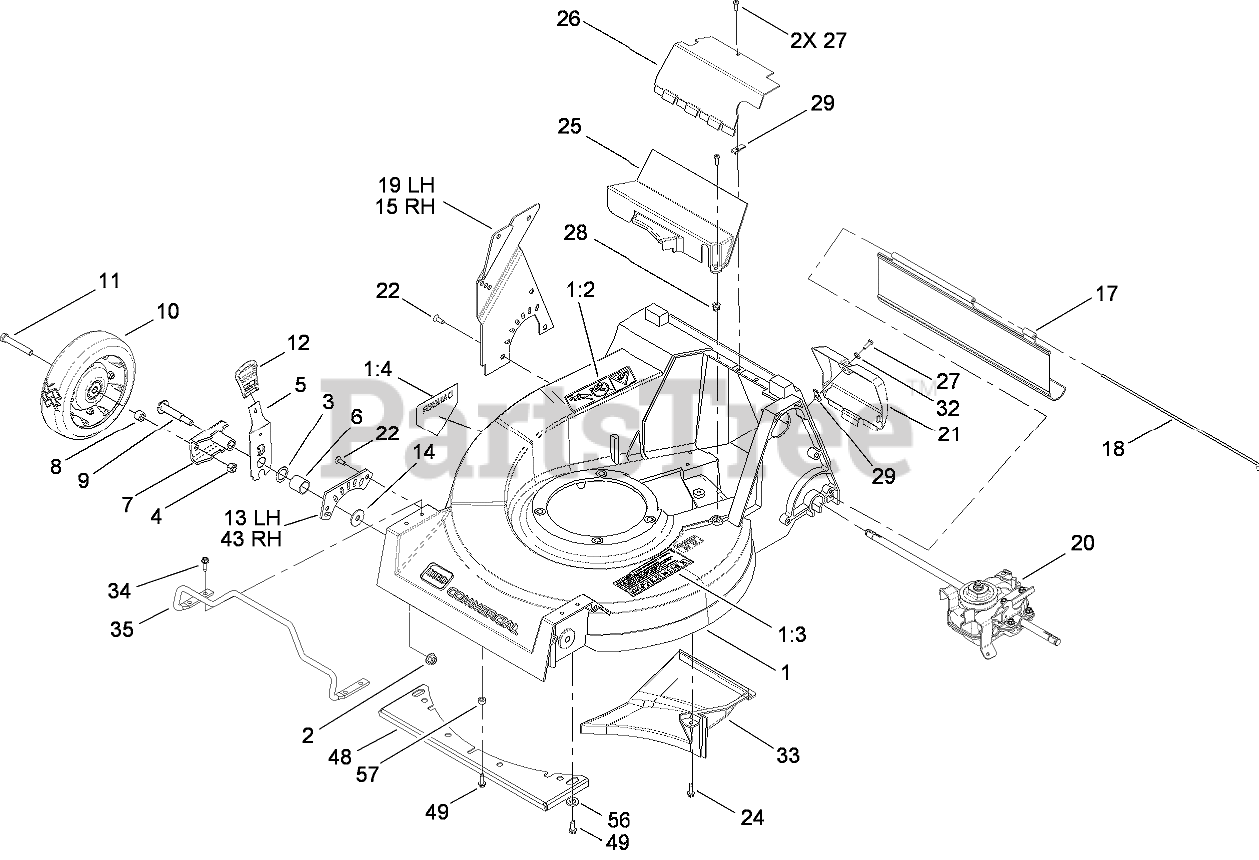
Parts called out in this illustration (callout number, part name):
1	DECK ASM
1:2	DECAL-DANGER
1:3	DECAL-DANGER
1:4	DECAL-DANGER
2	NUT-LOCK
3	WASHER
4	NUT-LOCK, CONE
5	FRONT SPRING ARM ASM
6	SPACER-BEARING
7	ARM-PIVOT, FRONT
8	SPACER-WHEEL
9	SCREW-SHOULDER
10	Wheel and Tire ASM
11	SCREW-HH
12	KNOB-HOC
13	PLATE-FRONT HOC, LH
14	WASHER
15	PLATE-REAR HOC, RH
17	SHEILD-TRAILING
18	ROD-SHIELD
19	PLATE-REAR HOC, LH
20	GEAR CASE ASM
21	DOOR-ACCESS, REAR
22	SCREW-HH
24	SCREW-HWHTF
25	COVER-BELT, LOWER
26	COVER-BELT, UPPER
28	NUT-CLIP
29	NUT-TYPE J
32	WASHER-FLAT
33	BAFFLE-CHUTE, FLOOR
34	SCREW-HWHTF
35	GUARD-ENGINE
43	PLATE-FRONT HOC, RIGHT
49	SCREW-HWHTF
56	WASHER-FLAT
57	TUBE-SPACER
